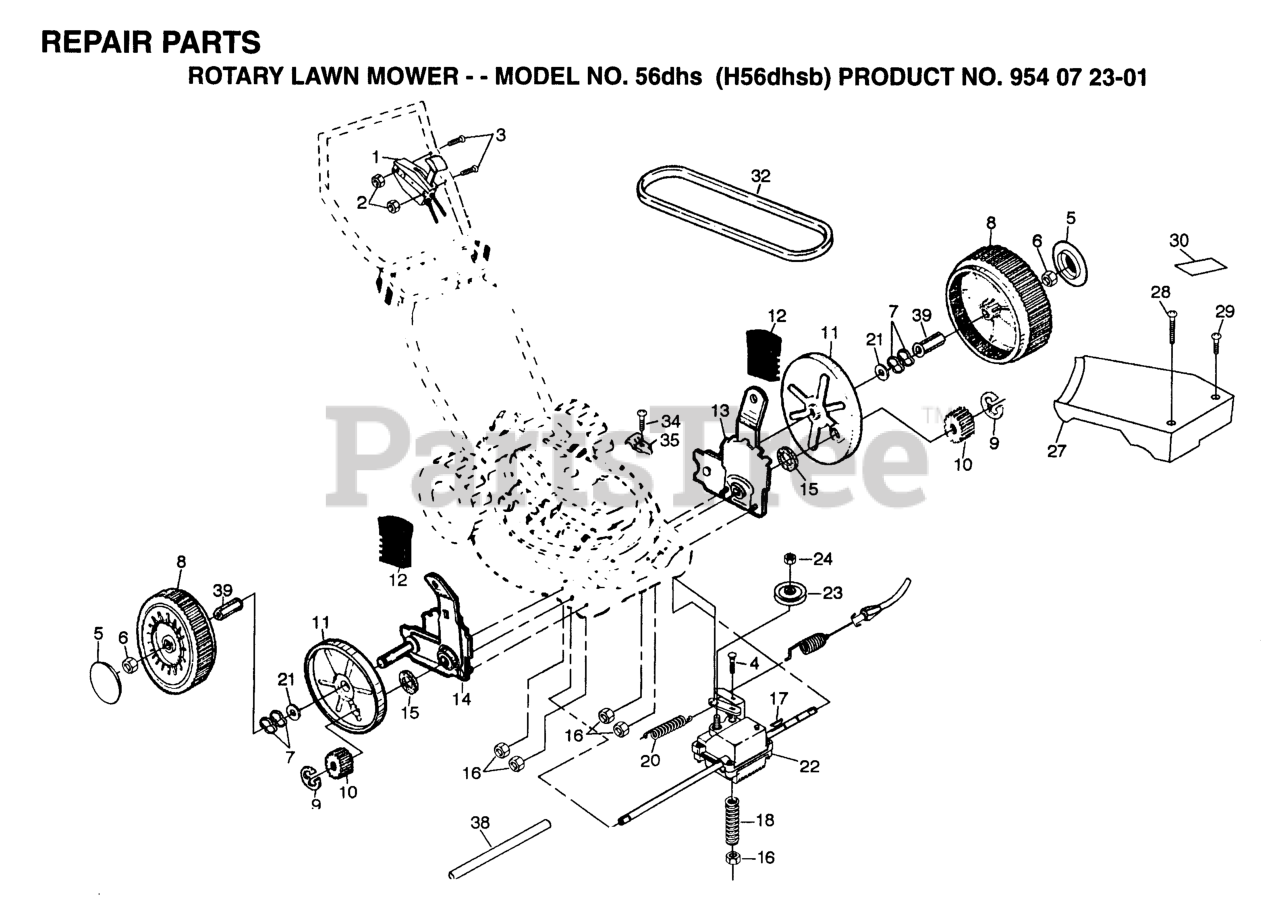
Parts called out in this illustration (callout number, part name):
1	DRIVE CONTROL
6	HEX FLANGE LOCKNT
7	WAVE WASHER
8	WHEEL AND TIRE ASSY
9	E-RING 7/16 RE
10	PINION GEAR
11	DUST SHROUD PM
12	SELECTOR KNOB
13	BRACKET-LH
14	BRACKET
16	NUT
17	HI PRO KEY
18	SPRING.EXTENSION
21	WASHER FLUT
22	KIT GEAR CASE .22SD
23	PULLEY
24	FLANGED LOCKNUT 3/8-16 ZINC
27	DRIVE COVER
29	SCREW
30	DECAL DRIVE COVER
32	BELT DRIVE
34	TAPPING SCREW
35	GUIDE CLIP PM
38	DRV SHAFT TUBE PM
39	BUSHING.1.860 X .505.
